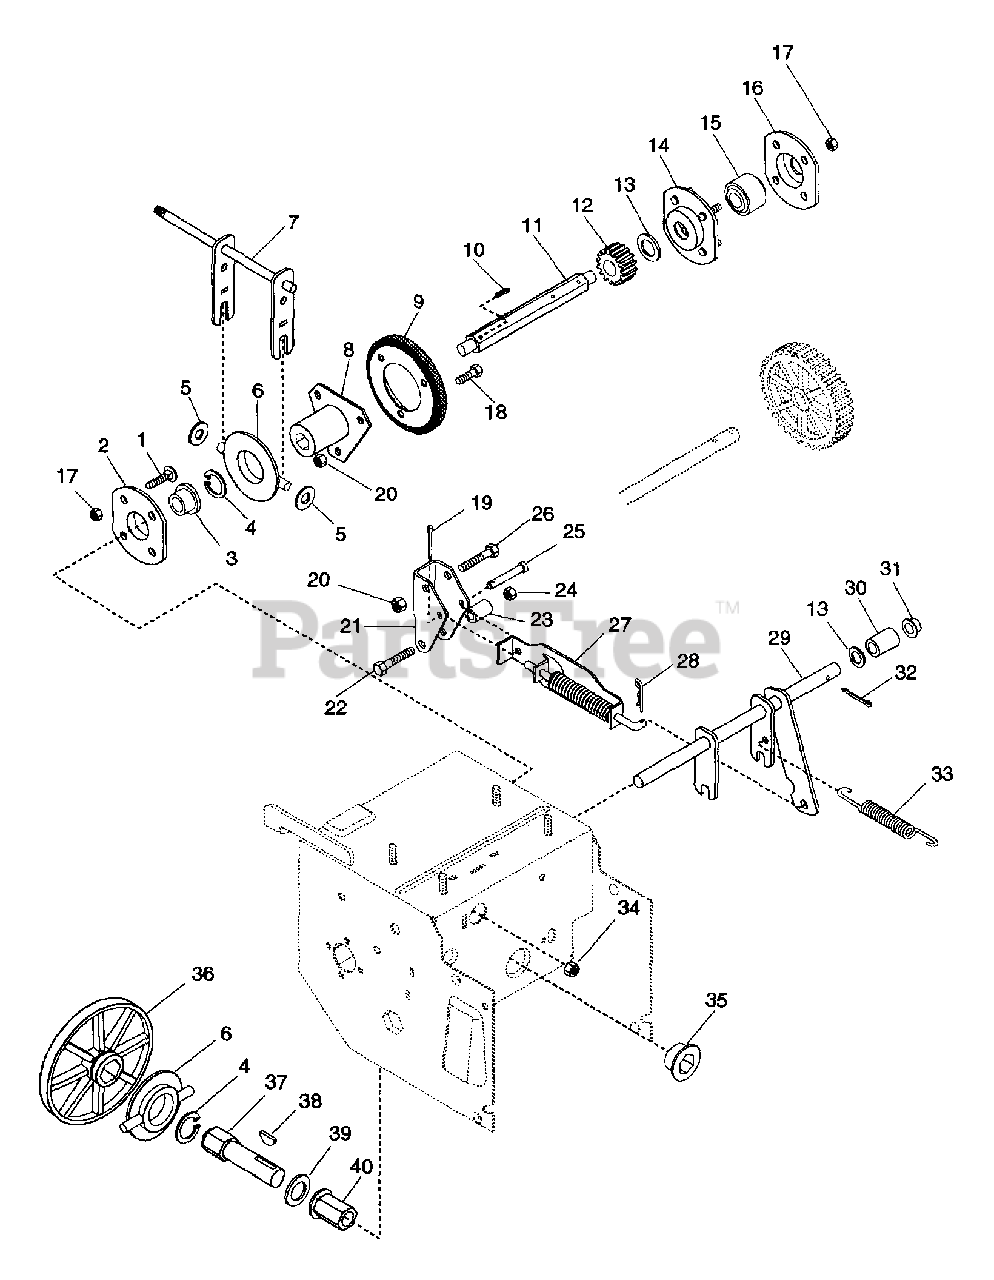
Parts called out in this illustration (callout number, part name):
1	BLT-RDHDSQNK 10-24X.38 PL
2	BEARING FLANGE
3	BSHG-FLG .500X.750X.625X.937
4	RG-RTNG-EXT 1.250X.050
5	WSHR-FL-STL .505X1.000X.062
6	BEARING ASSEMBLY
7	SHIFT FORK
8	FRICTION WHEEL HUB
9	FRICTION DISC
10	PIN-ROLL .125X.88
11	HEX SHAFT
13	LABEL, DANGER (FR OF M128466)
14	BEARING FLANGE
15	BRG-BALL .500X1.38X.437
16	BEARING FLANGE
17	NUT-LK DUAL FACE 10-24 PL
18	BLT-HEX .25-20X.50 PL GR2
19	PIN COTR .09X.50 PL
20	NUT-LK-CTR .250-20 PL
21	BRACKET
22	BLT-HEX .31-18X1.50 PL GR2
23	SPACER -SPLIT .340X.490X1.02
24	NUT-LK .312-18 GR A PL
25	CLEVIS PIN
26	BLT-HEX .25-20X1.75 PL GR2
27	TRACTION CLUTCH ASSEMBLY
28	PIN-HAIR INT .08X.18X1.18
29	CLUTCH FORK
30	BSHG, SPCR.500X.750X.321 PM
31	CAP, .50 ROD YWZC
32	PIN-COTR .12X1.0 PL
33	SG-TENS .063X.44X1.56
34	NUT-LK-CTR .375-16 GR A PL
35	BSHG-FLG .875X1.25X.75X1.50HX
36	FRICTION PLATE
37	HEX SHAFT
38	KEY-WDRF .188X.75X.313 SAE 9
39	WSHR, THRUST .625X1.125X.063
40	BSHG-FLG .625X.875X1.750X1.188
